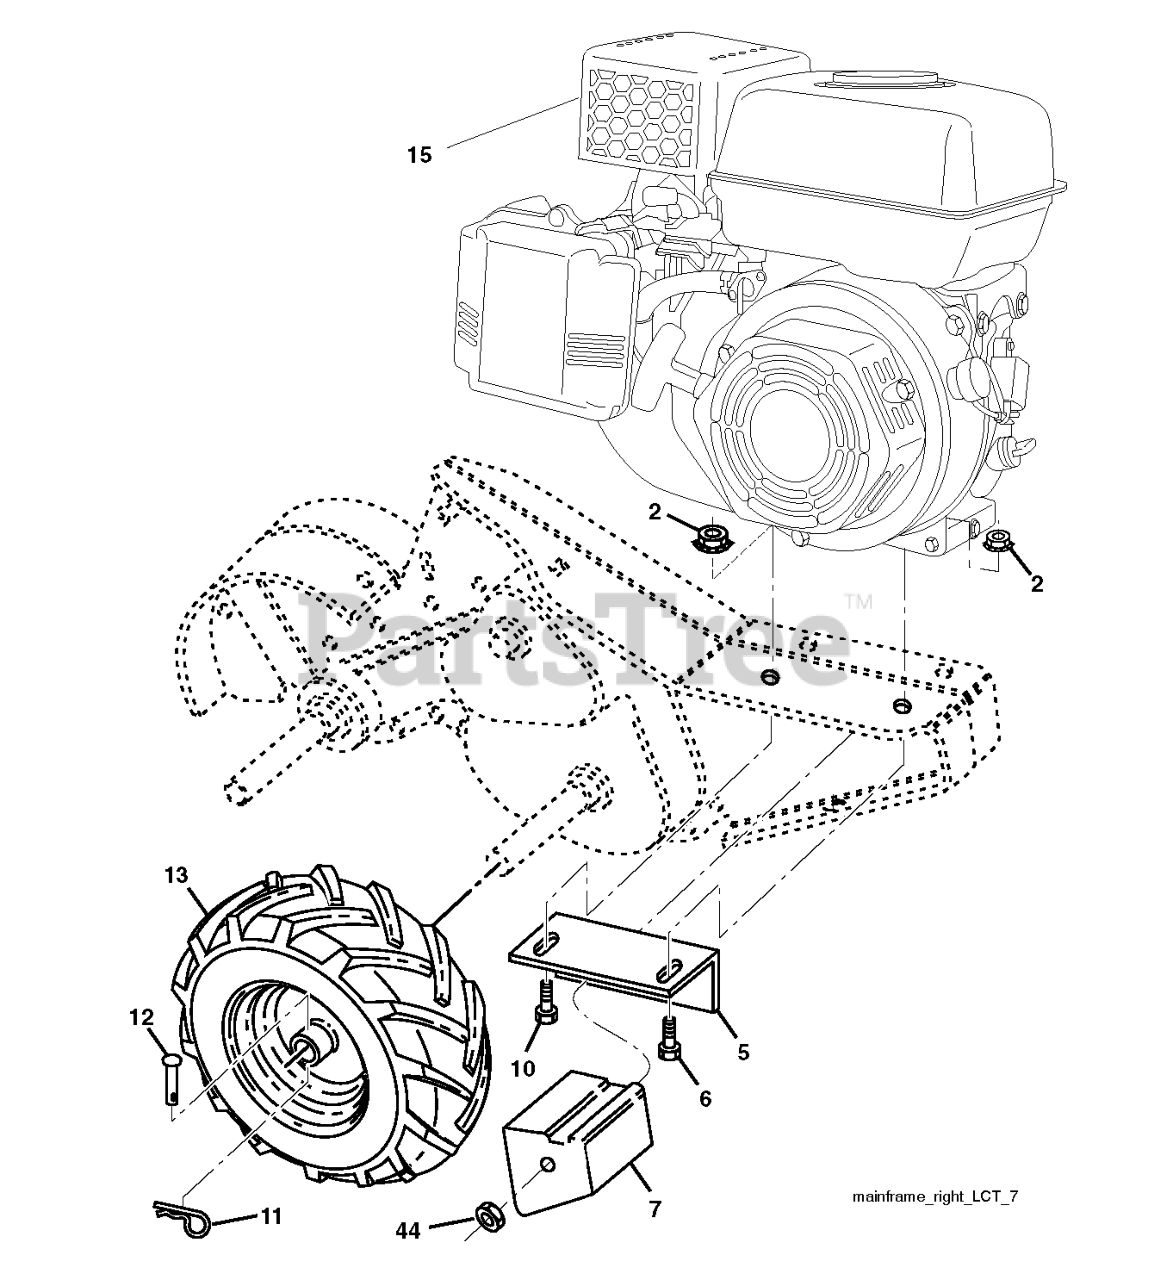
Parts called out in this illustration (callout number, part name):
2	LOCKNUT-FLANGE 5/16-18
5	BRACKET.REINFORCEMENT.RH.BLACK
6	BOLT, HEX 5/16-18X1-3/4
7	COUNTERWEIGHT.RH
10	BOLT
11	RETAINER M
12	RIVET,DRILLED
13	WHEEL.ASM.CRT.RH.13X5X6.SILVER
15	ENGINE LCT, 208CC, TILLER
